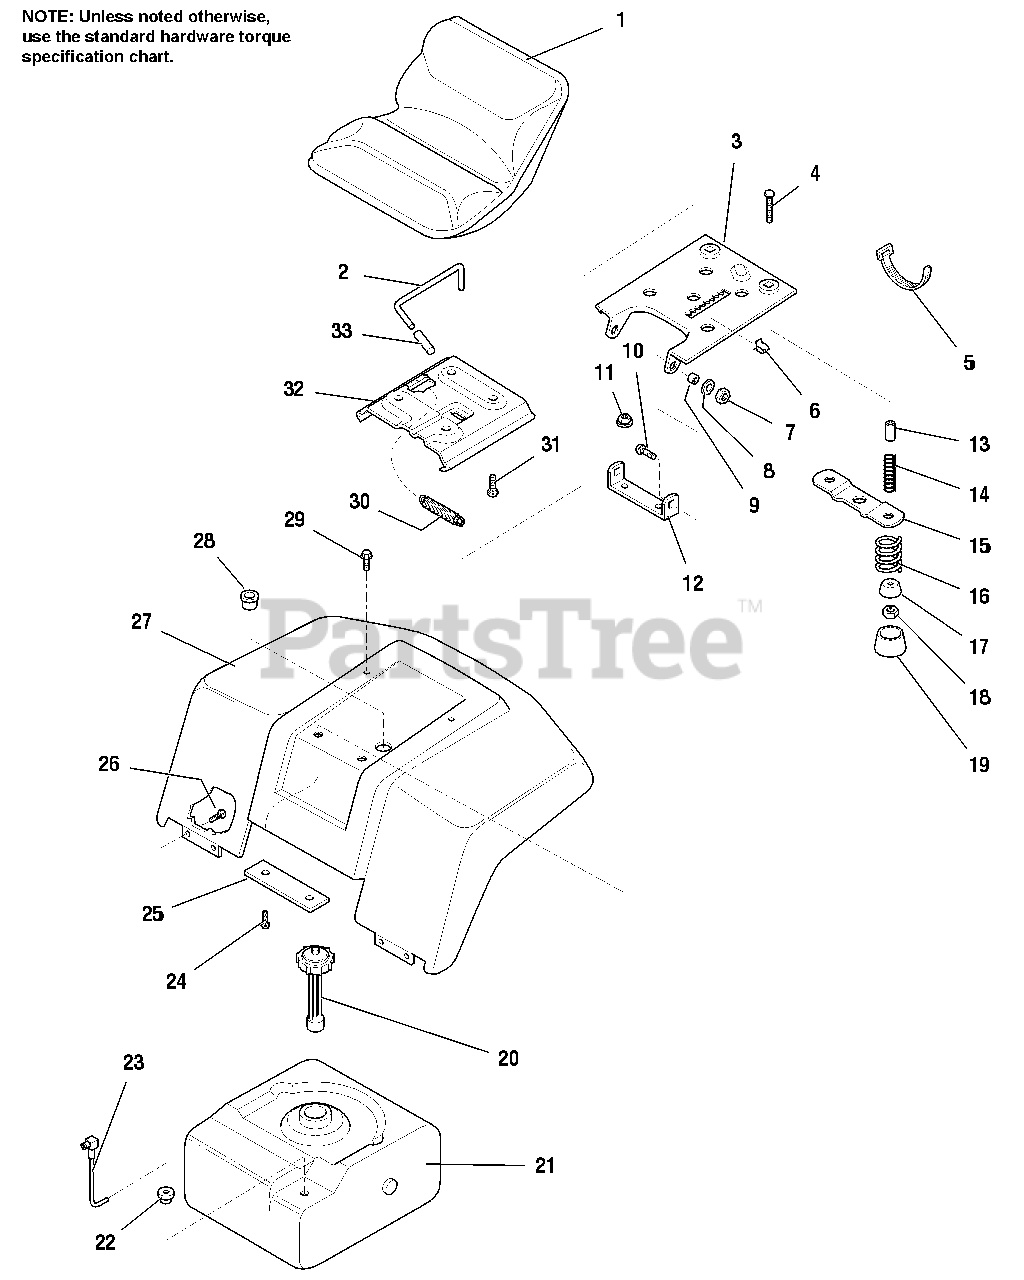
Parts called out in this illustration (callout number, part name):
1	SEAT, High-Back
2	LEVER, Seat Release
3	SUPPORT, Seat Pivot
4	CARRIAGE BOLT, 5/16-18 x 2
5	TIE, Self-locking, 15" long
6	CLIP, Speed
7	NUT, Hex Nylon Lock, 3/8-16
8	WASHER, Plain, 13/32
10	CARRIAGE BOLT, 3/8-16 x 1
11	NUT, Hex Flange, 3/8-16
12	BRACKET, Seat Pivot
14	SPRING, Compression
15	PLATE, Switch
16	SPRING, Compression
17	WASHER, Plain
18	NUT, Hex Nylon Lock, 5/16-18
19	COVER, Spring
20	CAP, Fuel Gauge
21	TANK, Fuel
23	ELBOW & TUBE ASSY.
24	CAPSCREW, Truss Hd., Torx drive, 3/8-16 x 1
25	PLATE, Reinforcement
26	CAPSCREW, Taptite, 1/4-20 x 1/2
27	SEAT DECK, Orange
27	SEAT DECK, Red
28	BUSHING, Snap
29	CAPSCREW, Taptite, 5/16-18 x 5/8
30	SPRING, Extension
31	CAPSCREW, Hex, Whizlock, 5/16-18 x 5/8
32	BRACKET, Seat Slide
33	HANDLE, Grip
